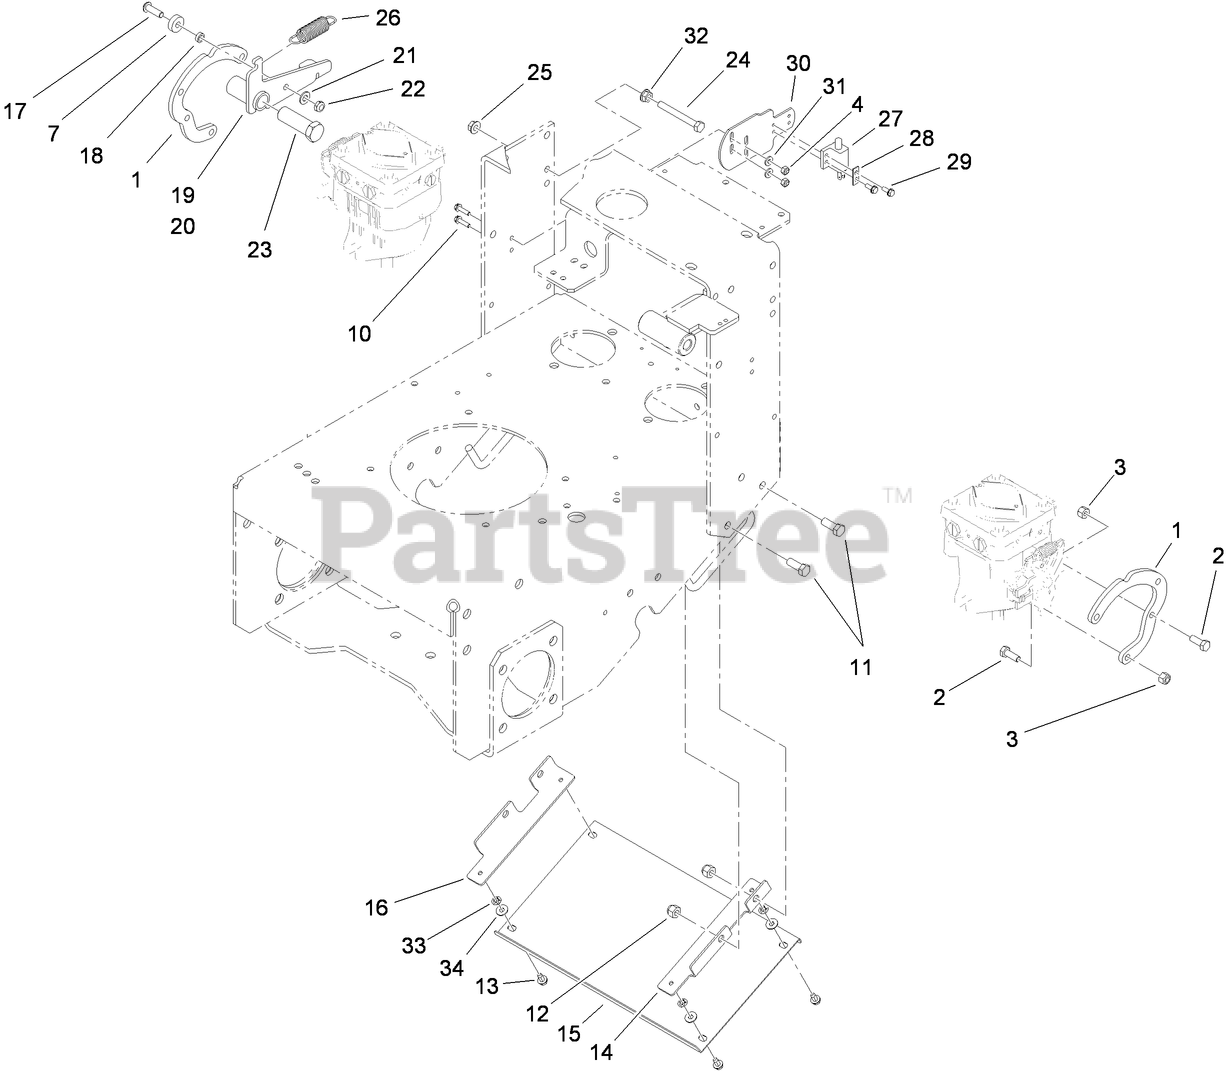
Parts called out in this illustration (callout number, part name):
1	BRACKET-ADAPTER, PUMP
2	SCREW-HH
3	NUT-LOCK, NI
4	NUT-LOCK, NI
7	BEARING-BALL
10	SCREW-HWH
11	SCREW-HH
12	NUT-LOCK, NI
13	SCREW
14	ANGLE-MOUNTING, LEFT
15	PANEL-BOTTOM
16	ANGLE-MOUNTING, RIGHT
17	SCREW-HSBH
18	SPACER-BEARING
19	RH DETENT ARM ASM
20	LH DETENT ARM ASM
21	WASHER-PLAIN
22	NUT-LOCK, NI
23	PIN-ADJUSTMENT, NEUTRAL
24	SCREW-HH
25	NUT-HF
26	SPRING-EXTENSION
27	SWITCH-CLOSED, NORMALLY
28	PLATE-SWITCH
29	SCREW-TAPTITE
30	BRACKET-NEUTRAL
31	WASHER-FLAT
32	NUT-HHF, SMOOTH
33	NUT-RETAINER
34	WASHER-FLAT
